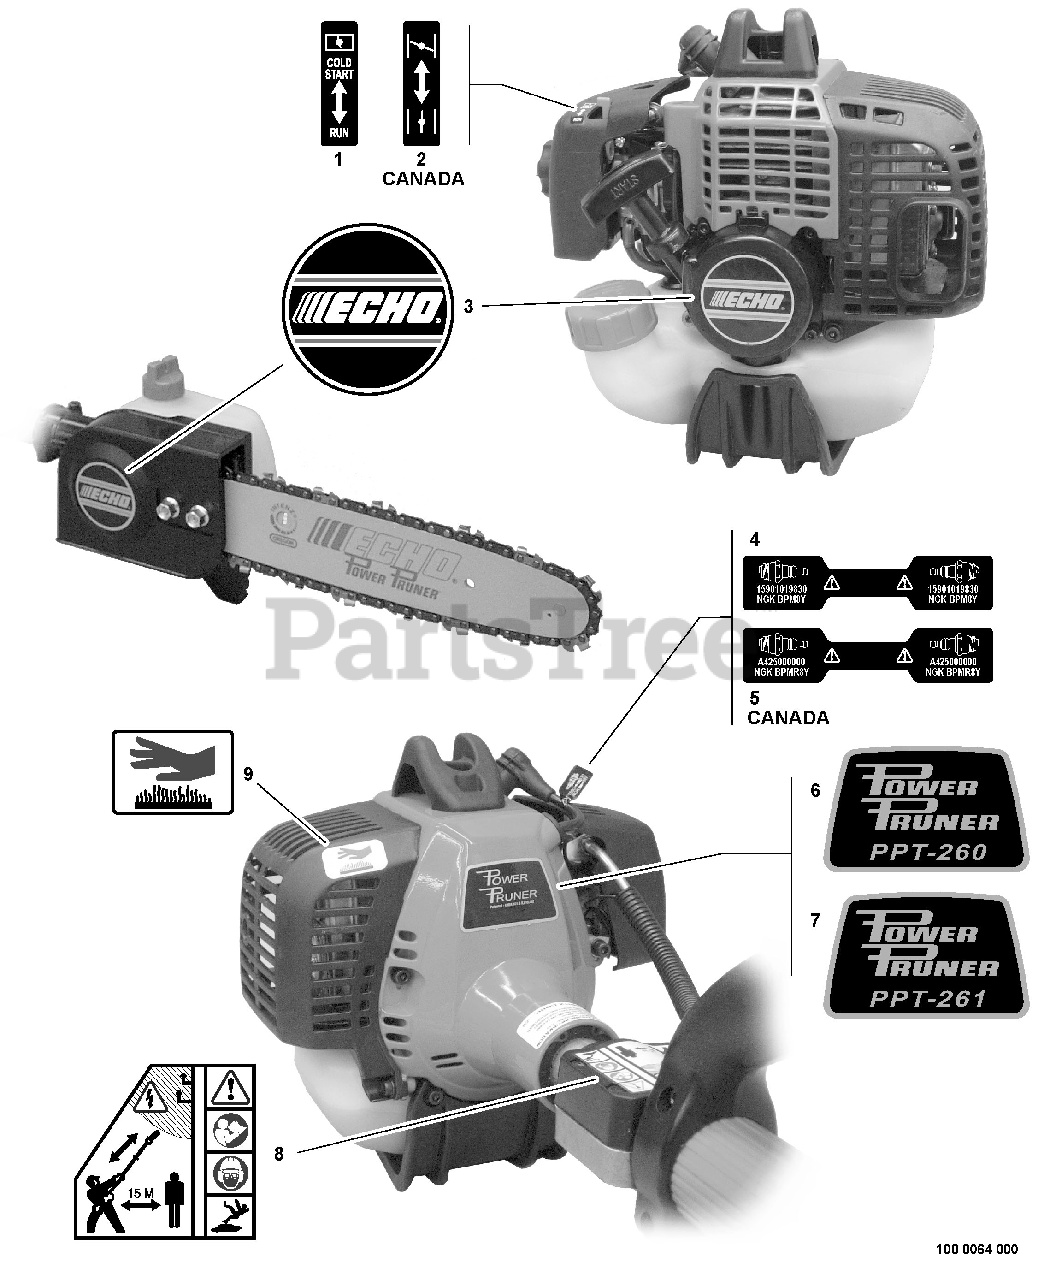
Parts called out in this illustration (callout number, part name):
1	LABEL - CHOKE
2	LABEL - CHOKE
3	LABEL - ECHO
4	LABEL - SPARK PLUG -- BPM-8Y
5	LABEL - SPARK PLUG -- BPMR-8Y
6	LABEL - MODEL PPT-260
7	LABEL - MODEL PPT-261
8	LABEL - CAUTION
9	LABEL - HOT SURFACE
